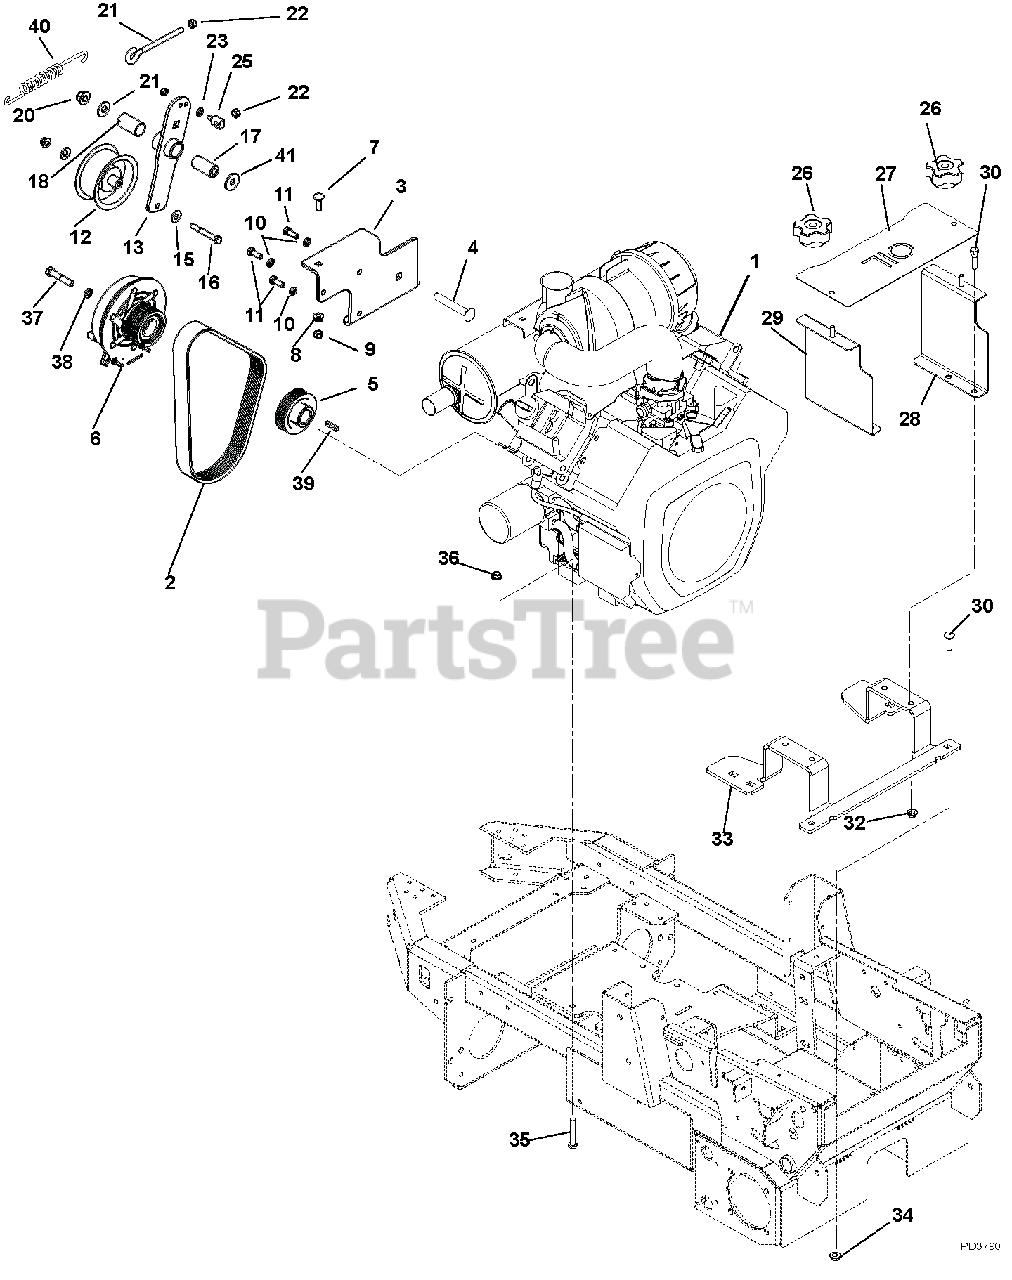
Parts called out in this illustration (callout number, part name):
1	ENGINE KOHLER 30 HP HORZ
2	BELT,8 RIB POLY V,L-SECTION
3	BRKT, PTO IDLER MTG.
4	@BLT-RDHDSQNK .50-13X3.50 G5YZ
5	SHEAVE - POLY-V 1.127 X 3.275
6	CLUTCH,8 GRV POLY V,L-SECTION
7	BLT-RDHDSQNK .38-16X1.25 G5YZ
8	@NUT-LK-NYL-FLG .38-16 YWZC
9	@NUT-LK-CTR .38-16 YWZC
10	@WSHR-LK .38X.094 REG YWZC
11	@BLT-HEX .38-16X1.00 GR5 YWZC
12	IDLER-FLAT 4.00X.38 (2.00 W)
13	ASM, IDLER PIVOT ASM
14	WMT,PTO IDLER PIVOT ARM (OFM)
15	@WSHR-FL-STL.438X1.00X.083 YWZ
16	@BLT-HEX .38-16X2.75 GR5 YWZC
17	BSHG, SPCR .502X.997X2.03 PM
18	BSHG, 1.00 X 1.125 X 1.937
19	WSHR-FL-STL .531X1.250X.10 YWZ
20	@NUT-LK-NYL-FLG .50-13 YWZC
21	BOLT,EYE .38-16X4.50,.75"EYE
22	@NUT-HEX .38-16 YWZC
23	@WSHR-FL-STL.344X.688X.065YWZC
24	NUT-LK-CTR .31-18 YWZC
25	PIN, PIVOT/TRUNNION
26	KNOB-CLAMPING, .312-18 NYLOC
27	SHROUD, COOLING
28	BRACKET, TANK SHROUD (LH)
29	BRACKET, TANK SHROUD (RH)
30	@BLT-HEX .38-16X1.50 GR5 YWZC
31	BLT-RDHDSQNK .38-16X1.00 G5YZ
32	@NUT-LK-NYL-FLG .38-16 YWZC
33	MOUNT, HYDRAULIC TANK
34	@NUT-LK-NYL-FLG .38-16 YWZC
35	@BLT-HEX .38-16X2.25 GR5 YWZC
36	@NUT-LK-TOP-FLG .38-16 YWZC
37	BLT-HEX .44-20X2.25 G5 YZ EP80
38	@WSHR-LK .44X.109 REG YWZC
39	KEY-SQ .25 X 1.25 X .25 SAE
40	SG-TENS .135X.69X5.75 WLD 150
41	WSHR-FL-STL.511X1.441X.125 YWZ
